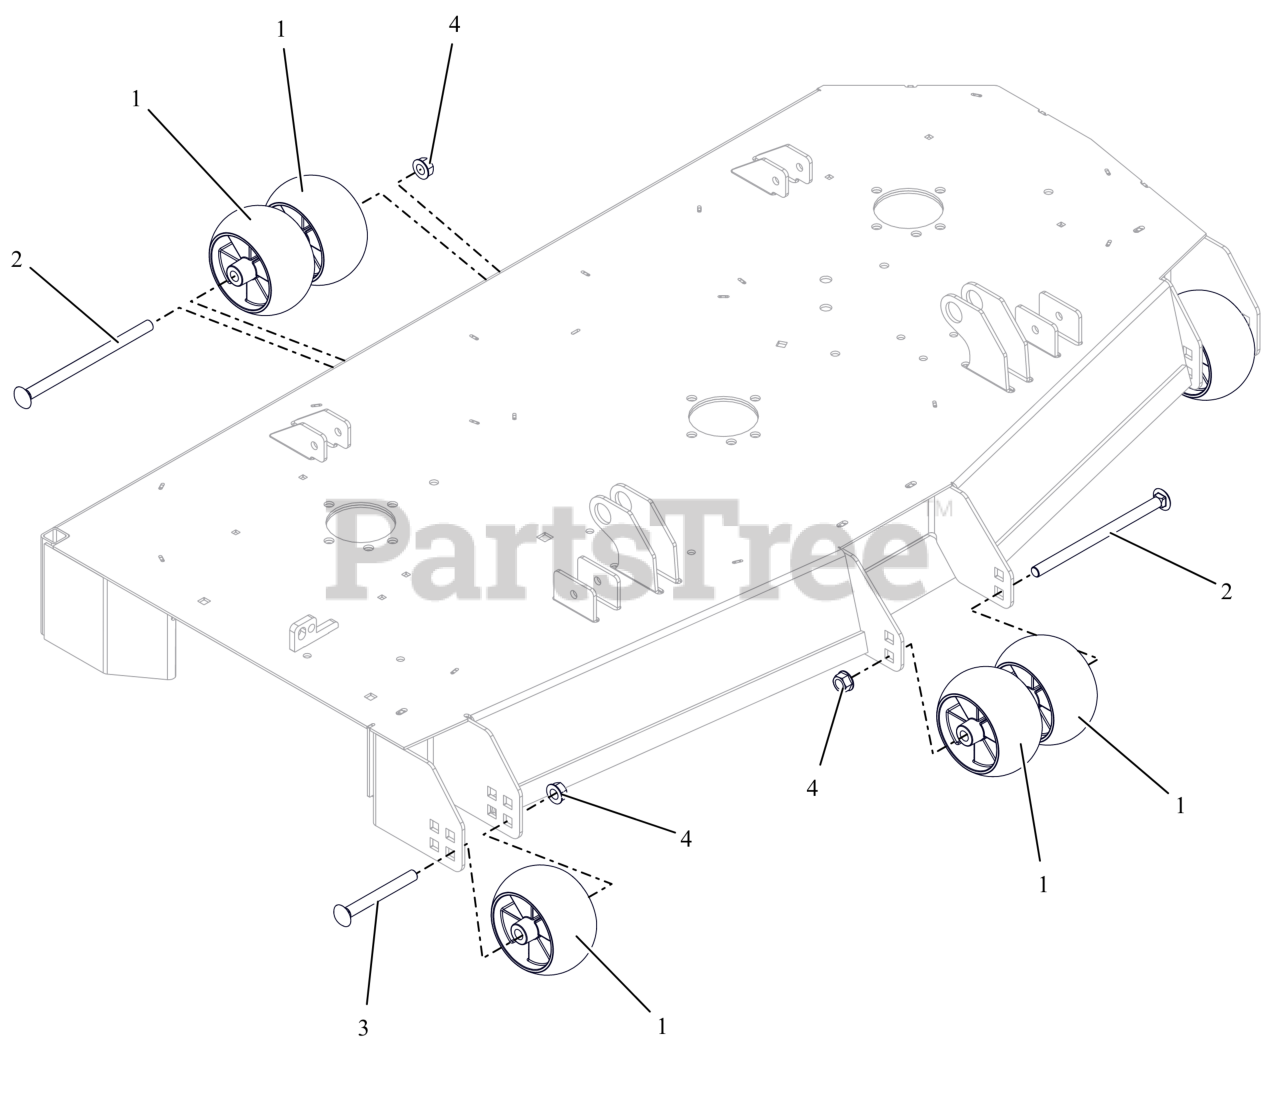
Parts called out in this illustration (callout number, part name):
1	WHEEL, ANTI SCALP - 5X3 CTR W/RIBS
2	BLT,RHSN .50-13X8.00 G5 ZCC NS
3	BLT,RHNS .50-13X4.50 G5 ZCC NS
4	NUT-LK-CTR-FLG .500-13 GG ZCC
